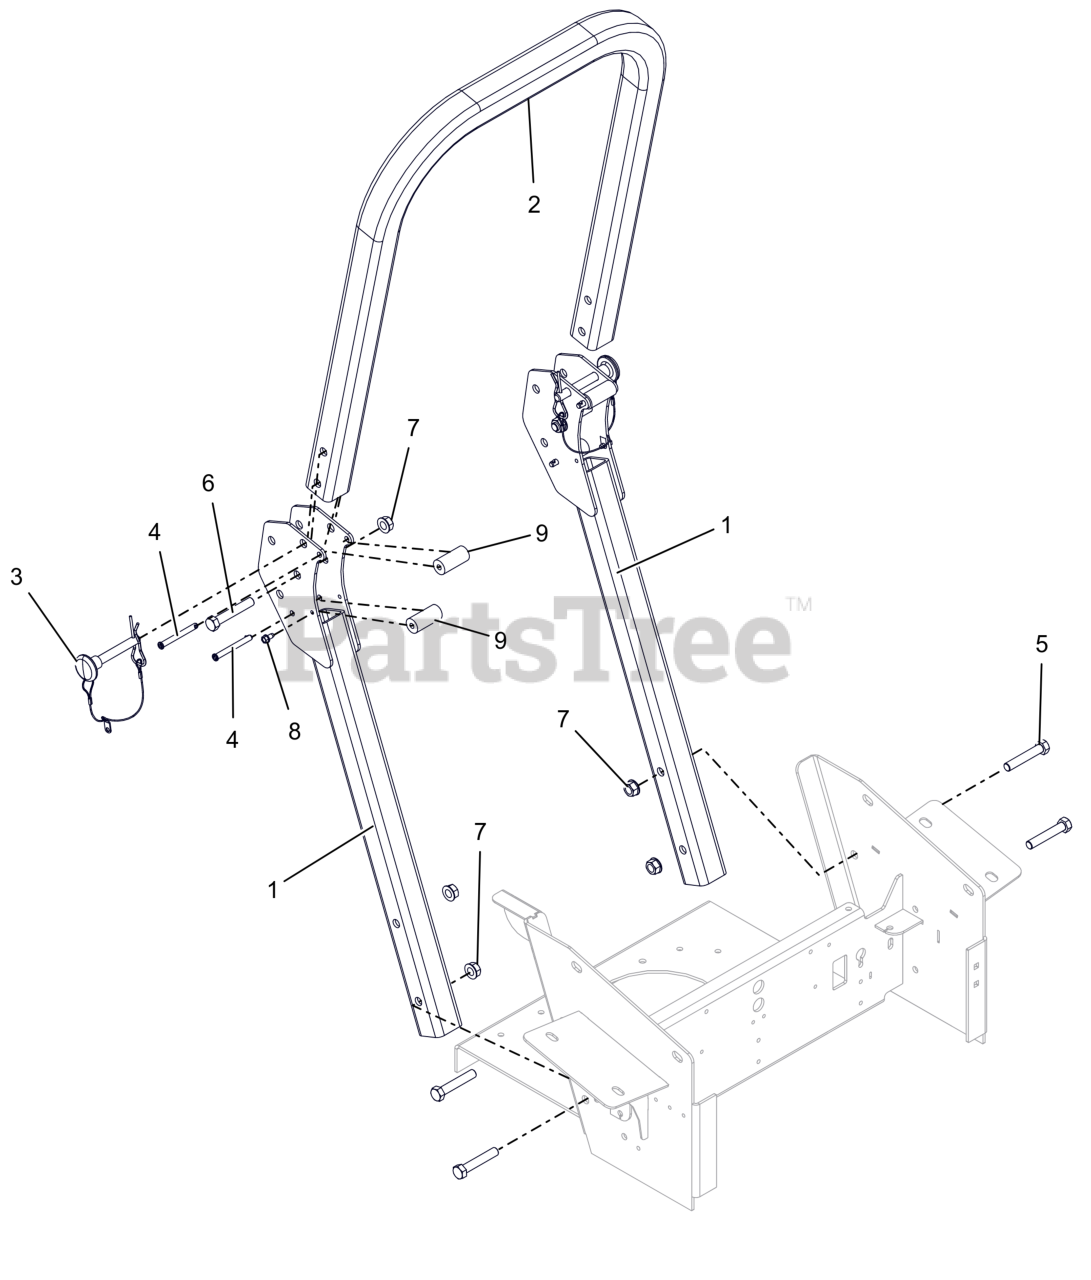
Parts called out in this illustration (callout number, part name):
1	WLDMT, PT/PT100 ROPS MTG POST
2	HOOP, ROPS
3	PIN, ROPS W/LANYARD
4	PIN, SLIC .312 X 2.570
5	BLT,HEX .50-13X2.75 G5 ZCC
6	BLT, HEX .50-13X3.00 G5 ZCC
7	NUT-LK-CTR-FLG .500-13 GG ZCC
8	SCR-TAP .25-20X.50 HWH ZCC
9	BUMPER, ROPS ANTI-VIBRATION
